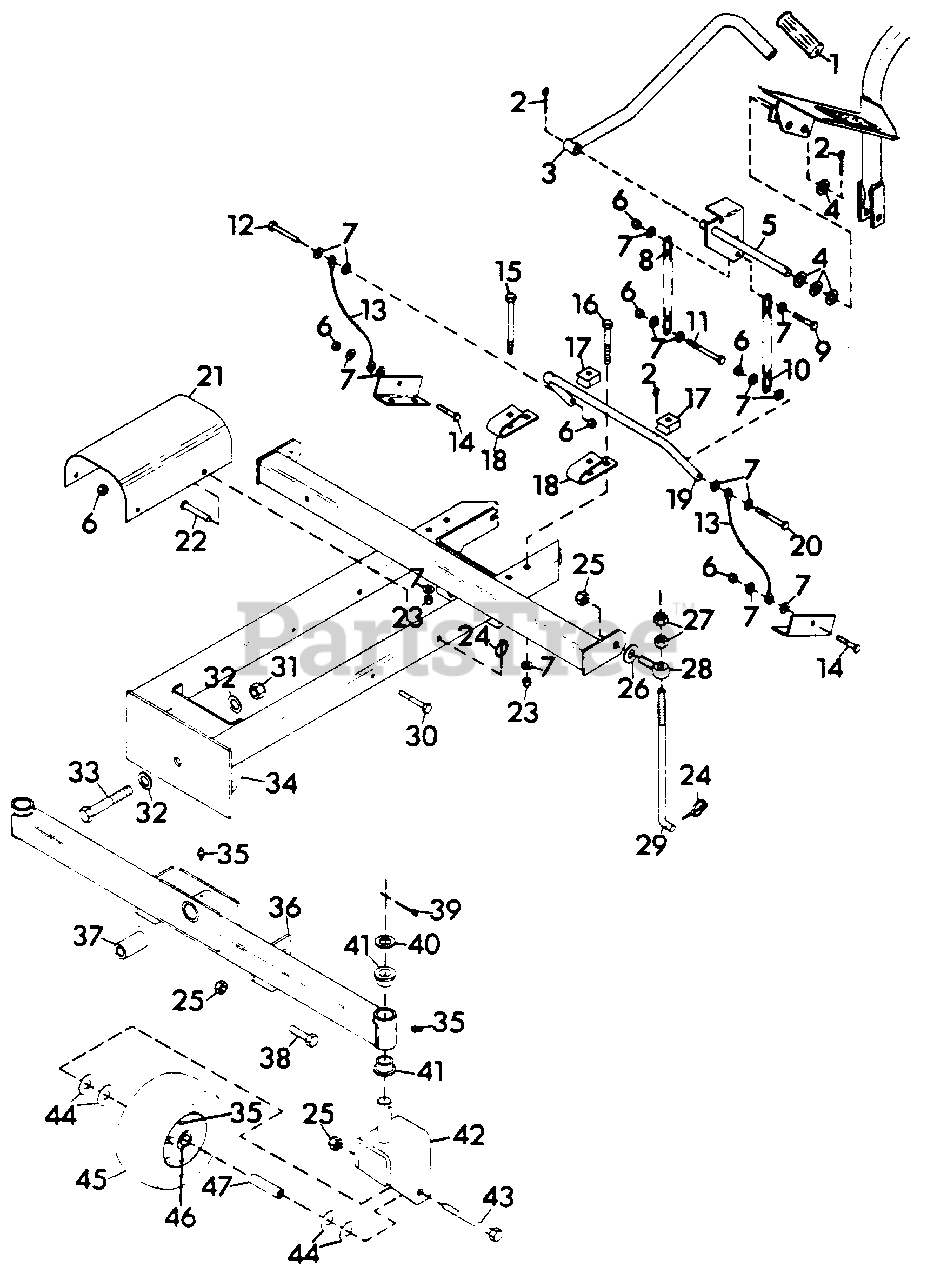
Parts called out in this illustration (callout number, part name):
1	SEAT, HIGH BACK
2	SPRING, SEAT
3	BOLT, 5/16-18X1.00 RD HD SQ NK
4	BOLT, HEX 5/16-18X.75
5	WASHER, LOCK 5/16
6	GROMMET, PLASTIC
7	WASHER, FLAT .344X.688X.065
8	SCREW, TAPPING 1/4-20X.625
9	COVER, CHAIN
10	BEARING, FLANGED
11	FITTING, LUBE 1/4-28
12	BOLT, HEX 3/8-16X2.75
13	NUT, LOCK 3/8-16
14	TUBE, SUPPORT
15	WELDMENT, WEIGHT BOX
16	BOLT, HEX 3/8-16X2.25
17	WASHER, FLAT .406X.812X.065
18	TUBE, STEERING
19	BOLT, 3/8-16X1.00 RD HD SQ NK
20	NUT, LOCK 5/16-18
21	FRAME, O.F.C.
22	COVER, LARGE FOOTBOARD
23	PIN, COTTER .125X1.500
24	BUSHING
25	PIN, .750X3.3
26	BOLT, HEX 1/2-13X5.50
27	BRACKET, MOUNT
28	PLATE, AXLE
29	NUT, LOCK 1/2-13
NS	DECAL, GRAVELY LOGO
NS	DECAL, PRO MASTER-50
NS	DECALS, OFC
NS	DECAL, AMERICA
